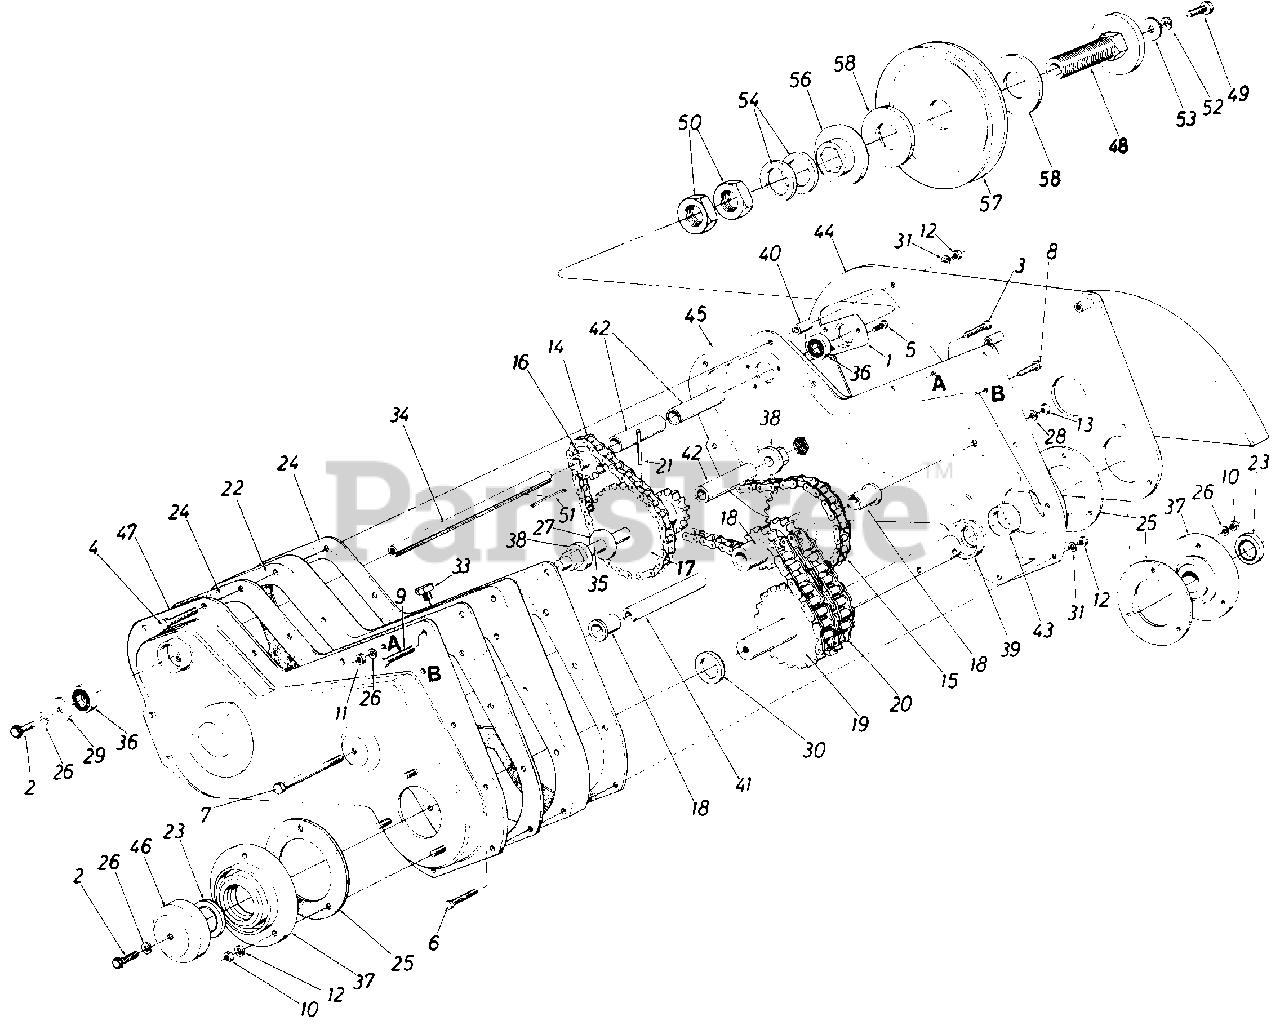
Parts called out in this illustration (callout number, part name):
1	Bearing Housing 1-3/8" Dia.
2	Hex Bolt 5/16-18 x .88" Lg. Spec.
3	Hex Bolt 5/16-18 x 1.50" Lg.*
4	Hex Bolt 1/4-20 x 2.75" Lg.*
5	Hex Wash. S-Tap. Scr. 1/4-20 x .50" Lg.
6	Hex Bolt 1/4-20 x 1.50" Lg.*
7	Hex Bolt 3/8-16 x 4.5" Lg.
8	Hex Wash. Hd. Bolt 1/4-20 x 1.5" Lg.
9	Hex Wash. TT Tap Scr. 5/16-18 x 1.75" Lg.
10	Hex Cent. L.-Nut 5/16-18 Thd.
11	Hex Nut 5/16-18 Thd.*
12	Hex Nut 1/4-20 Thd.*
13	Hex Nut 3/8-16 Thd.*
14	#41 Chain 1/2" Pitch x 34 Links-Endless
15	#42 Chain 1/2" Pitch x 48 Links-Endless
16	Sprocket 10 Tooth .500" Pitch
17	10 & 28 Teeth Sprocket Ass'y.
18	8-2 & 28 Sprocket Sleeve Ass'y.
19	18-2 Sprocket Shaft Ass'y.
20	#50-2 Chain 5/8" Pitch x 28 Links-Endless
21	Spring Pin Spir. 1/4" Dia. x 1.50" Lg.
22	Spacer Block-Tiller Housing
23	Oil Seal Double Lip-1-1/4" Dia.
24	Gasket for Tiller Housing
25	Gasket for Brg.-Housing
26	L.-Wash. 5/16" I.D.*
27	Fl.-Wash. .640" I.D. x 1.24" O.D.
28	L.-Wash. 3/8" I.D. Heavy Duty
29	Fl.-Wash. .344" I.D. x.1.125"
30	Special Washer
31	L.-Wash. 1/4" I.D.*
33	Vent Plug
34	Jack Shaft .525" I.D. x 7.78 " Lg.
35	Sprocket Shaft .63" Dia. x 5.0" Lg.
36	Ball Brg. .62" I.D. x 1.38" O.D.
37	Bearing Housing- 1-1/4"
38	Hex Flange Brg.
39	Spacer 1.25" I.D. x 2.0" O.D.
40	Spacer.28" I.D. x .62" O.D. x .90" Lg.
41	Spacer .38" I.D. x .62" O.D. x 3.44" Lg.
42	Spacer.62" I.D. x .88" O.D. x 1.56" Lg.
43	Spacer 1.25" I.D. x 1.62" O.D. x.50" Lg.
46	Dust Cap .320" Dia. Hole
49	Hex Bolt 5/16-18 x 1.25" Lg. Grade 5
50	Hex Jam Nut l.0-14 x 28 Thd.
51	Sq. Key 3/16 x 1.50" Lg.
52	L.-Wash. 5/16" I.D.*
53	Fl.-Wash. .344" I.D. x 1.125" O.D.
54	Spring Bell Wash. 1.0" I.D. x 2.0" O.D.
56	Floating Disc 3-1/4" O. D. x 1.0" I.D.
57	5/8 V-Pulley 1.50" I.D. x 6.50"
58	Friction Pad 3-1/4" O.D. x 1-3/8" I.D.
